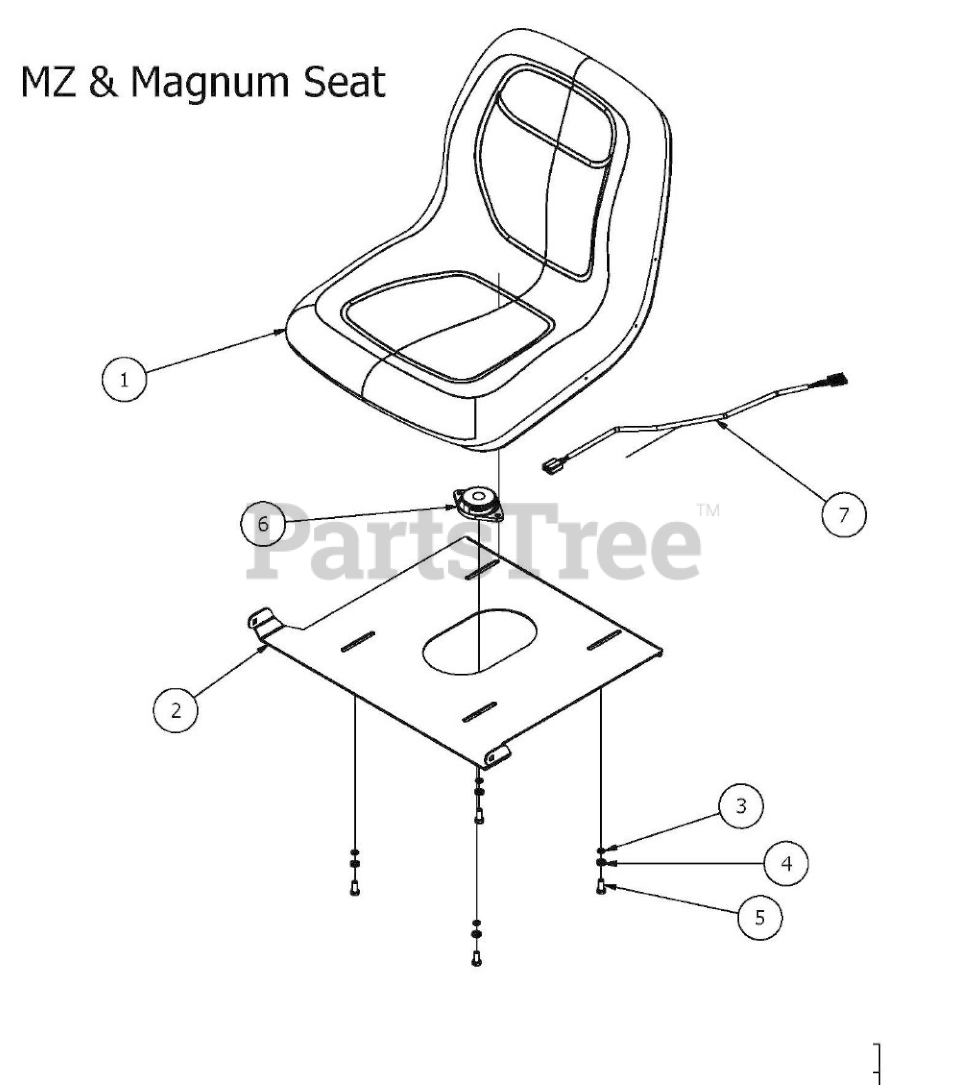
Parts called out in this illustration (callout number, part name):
2	2017 MZ Seat Plate
3	1/4 Flat Washer
4	5/16" Lock Washer
5	5/16" x 3/4" Hex Bolt
6	SeatSafteySwitch
7	Seat Switch Adapter
